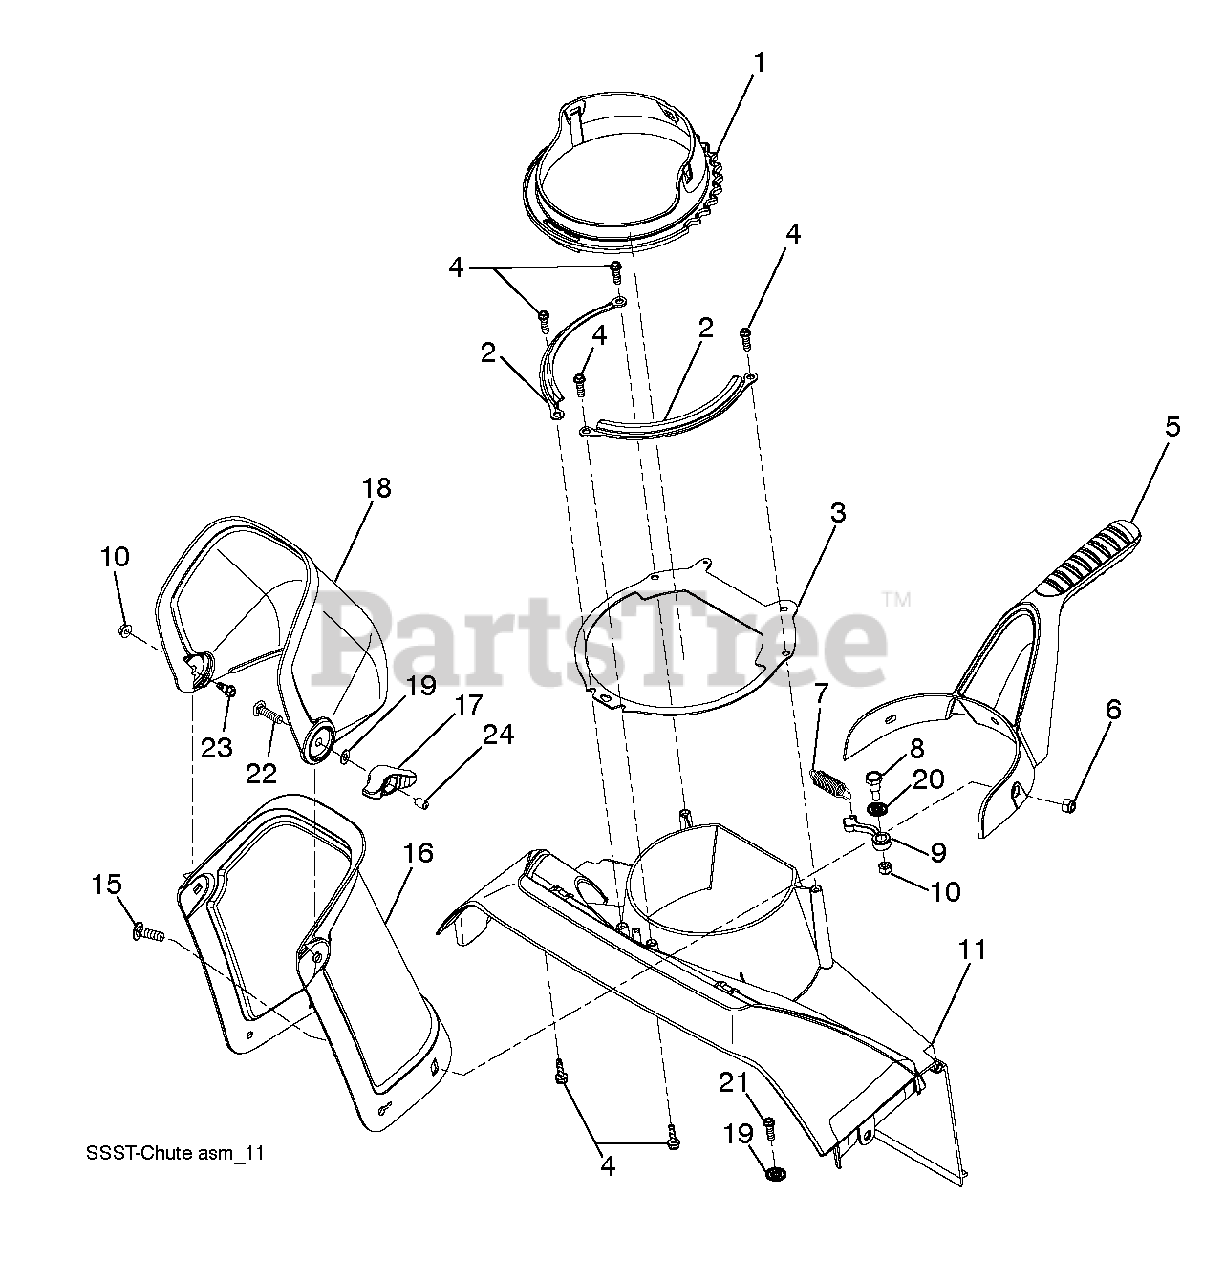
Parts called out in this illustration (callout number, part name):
1	CHUTE.RATCHETING.PLASTIC.W/GRV
2	PLATE.CHUTE.RETAINER
3	PLATE.CHUTE.BASE
4	SCREW.HX.13X.750
5	HANDLE.CHUTE.BLACK
6	LOCKNUT-FLANGE 5/16-18
7	SPRING.RATCHET.ARM
8	SHOULDER BOLT ST
9	ARM.CHUTE.RATCHET
10	NUT
11	PLENIUM.AUGER.POULAN PRO.BLACK
15	BOLT.CARR.5/16-18X1.BLACK
16	CHUTE.SINGLE.STAGE.SNOW.BLACK
18	DEFLECTOR.CHUTE.BLACK
20	WASHER.13/32X1-1/2X16GA
21	BOLT.HEX.HD.WASHER.5/16-18X.75
22	BOLT.CARRIAGE.5/16-18
23	BOLT.SHOULDER.HEX.HD.1/4-20
24	PLUNGER CAP
